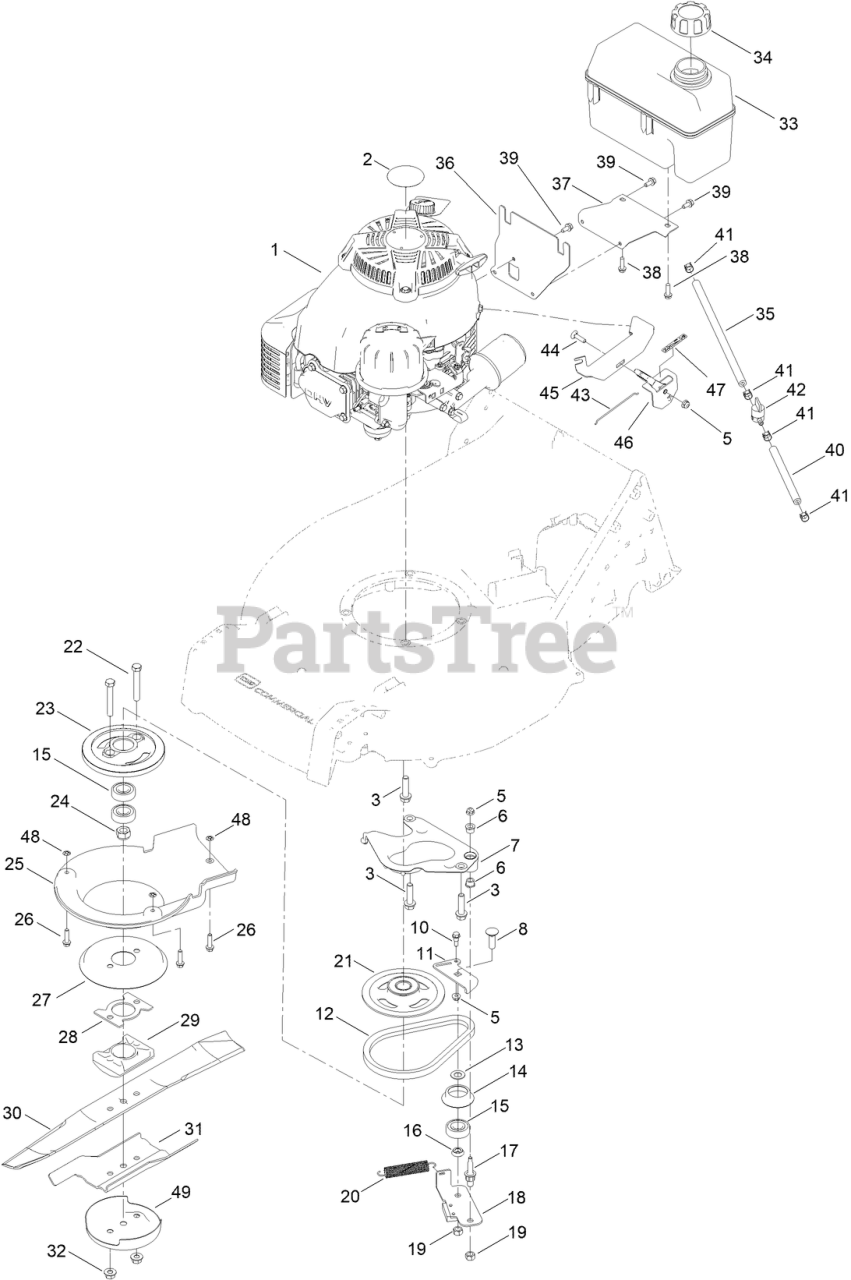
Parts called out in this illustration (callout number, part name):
3	SCREW-HWH
5	NUT-HF
6	BUSHING-FLANGE
7	PLATE-ANCHOR
8	BOLT-CARR
10	BOLT-SHOULDER
11	PLATE-GUIDE, BBC
13	SPACER
14	RETAINER-BELT
15	BEARING-BALL
16	SPACER-BEARING
17	BOLT-SHOULDER
18	PLATE-BRAKE
19	NUT-HEX
20	SPRING-TENSION, BRAKE
21	PULLEY
22	SCREW-HH
24	NUT-HEX
26	SCREW-HWHTF
28	SPACER-DRIVER, BLADE
29	SUPPORT-BLADE
30	BLADE-21IN, RECYCLING
31	ACCELERATOR-BLADE
32	NUT-FLANGE, LOCK
33	TANK-FUEL
34	CAP-GAS
35	HOSE-FUEL
36	BRACKET-TANK, MOUNTING
37	BRACKET-TANK, SUPPORT
38	SCREW-HWH
39	SCREW-HWH
40	HOSE-FUEL
41	CLAMP-HOSE
42	VALVE-FUEL
43	WIRE-CONTROL
44	SCREW-CARR
45	BRACKET-MOUNT, THROTTLE
46	CONTROL-THROTTLE
47	DECAL-THROTTLE, CHOKE
48	PUSHNUT-RETAINER, BOLT
49	CUP-ANTI SCALP
